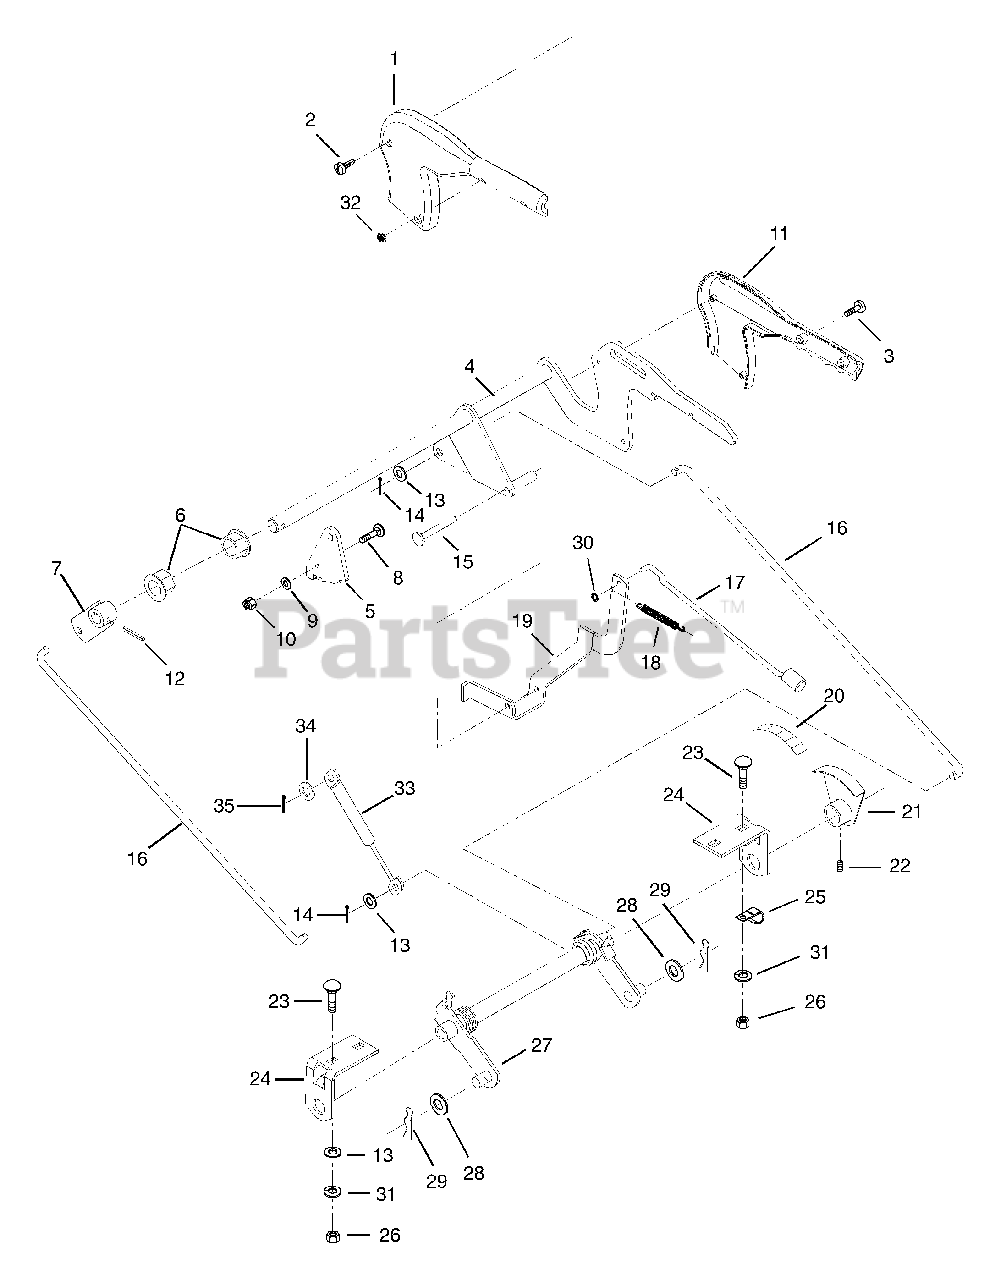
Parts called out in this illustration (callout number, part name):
1	COVER - LIFT RH
2	SCR-TAP 10-16X1.125HI-LOTPHBL
3	SCR-MCH 10-24X.62 P/HD
4	LEVER, LIFT
5	QUADRANT - LIFT
6	BSHG-FLG .750X.873HEXX.53X1.18
7	ARM, LIFT
8	@BLT-RDHDSQNK .31-18X.75 G5YZ
9	WSHR-FL-STL .323X.625X.062 YWZ
10	@NUT-LK-CTR .31-18 YWZC
11	COVER - LIFT LH
12	PIN-GRV .250X1.25 TP A
13	@WSHR-FL-STL.406X.812X.065 YWZ
14	@PIN-CTR .12X1.00 EXTPRSQCT YZ
15	PIN, PIVOT .312 X 2.56
16	LINK, LIFT
16	LIFT LINK
17	PIN, LIFT
18	SG-TENS .048X.44X2.25 WLD 9
19	LEVER - DETENT
20	DECAL - INDICATOR 5 POS
21	INDICATOR - DECK HEIGHT
22	SCR-SET .25-20X.25 SKHCUP OH
23	BLT-RHHDSQSHNK .38-16X.75 G2YZ
24	BRACKET - CENTER LIFT
25	J-CLAMP
26	@NUT-HEX .38-16 YWZC
27	LEVER - CENTER LIFT
28	WSHR-FL-STL .630X1.005X.062 YZ
29	PIN-HAIR-EXT .12X.31X2.37 YWZC
30	RG-RTNG-EXT .250X.010
31	@WSHR-LK .38X.094 REG YWZC
32	NUT,10-24 LOW CROWN, ACORN
33	SG-GAS COMP .315X.75X10.00 120
34	@WSHR-FL-STL.38X.875X.083 YWZC
35	@PIN-CTR .12X.75 EXTPRSQCT YWZ
